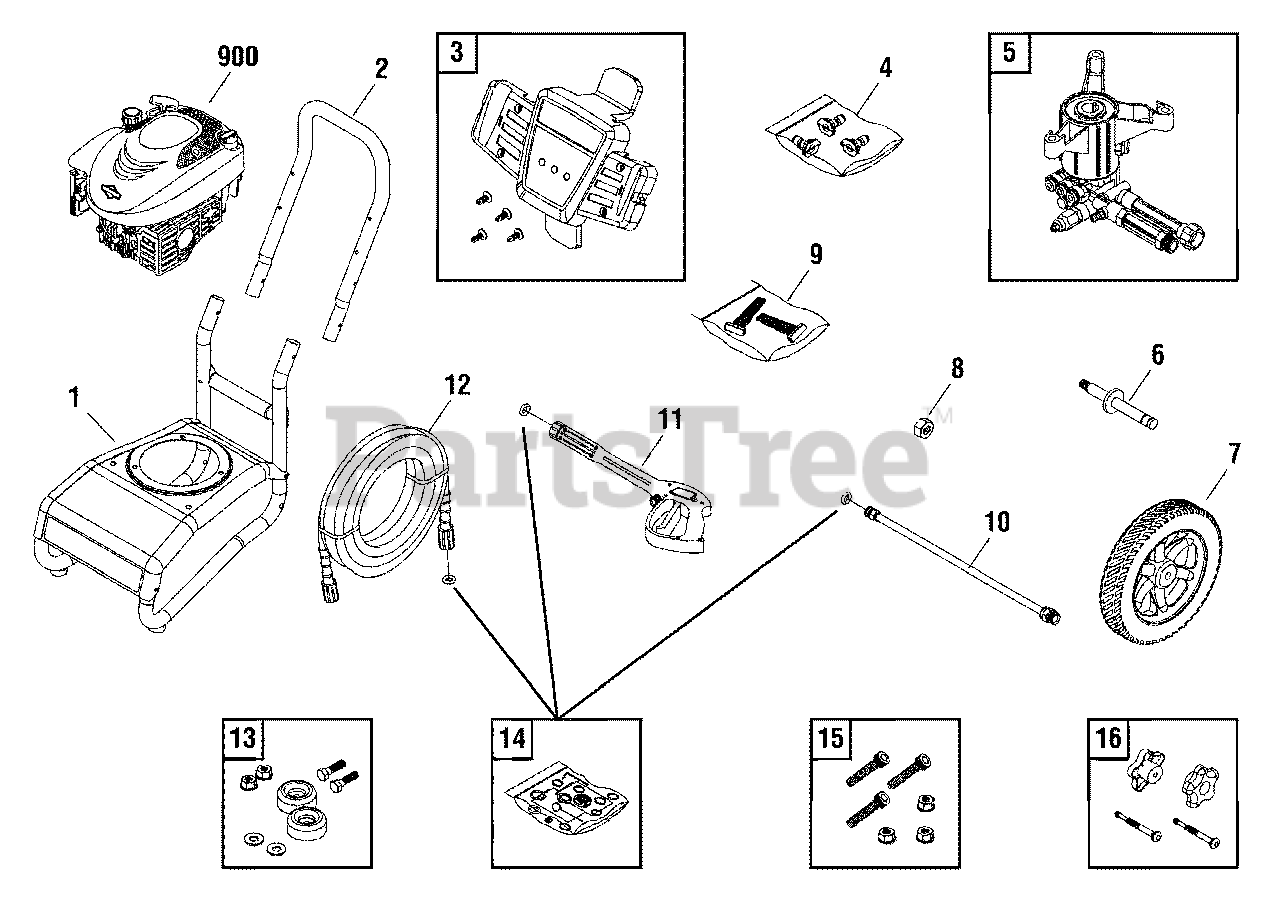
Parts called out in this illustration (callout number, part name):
1	BASE
5	PUMP
8	NUT
10	EXTENSION, QC
11	GUN
12	HOSE
13	MOUNT, Vibration
14	KIT, O-Ring
15	KIT, Hardware, Pump Mounting
